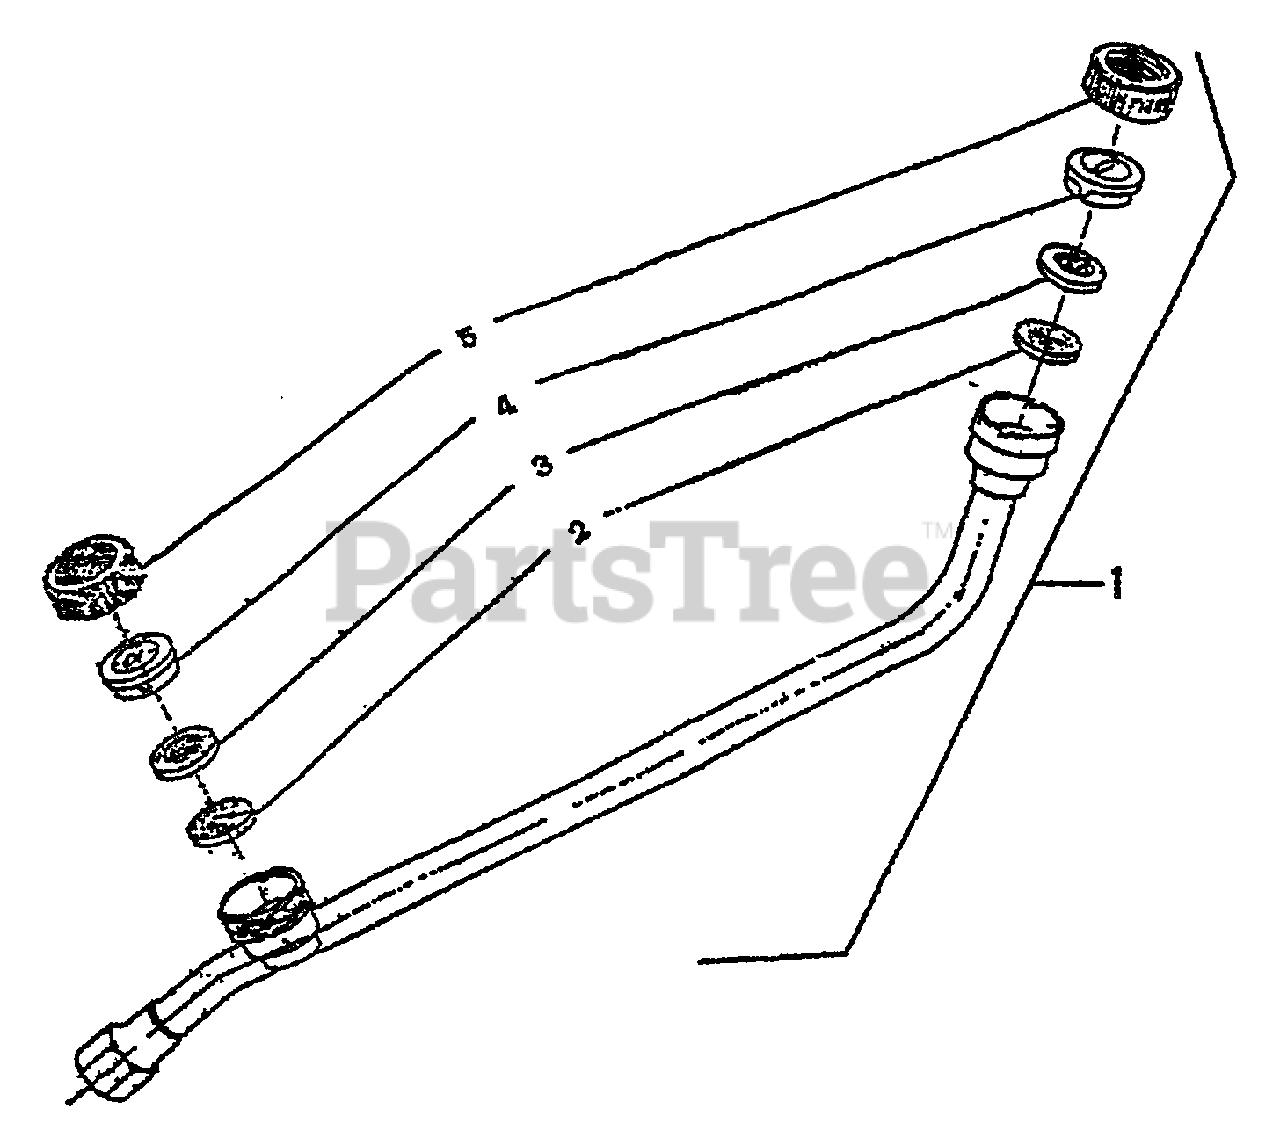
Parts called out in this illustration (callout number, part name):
1	LINE NOZZLE ASSY - 2 HEAD
2	GASKET, NOZZLE
3	GASKET, NOZZLE
4	PLATE, NOZZLE
5	CAP, NOZZLE
